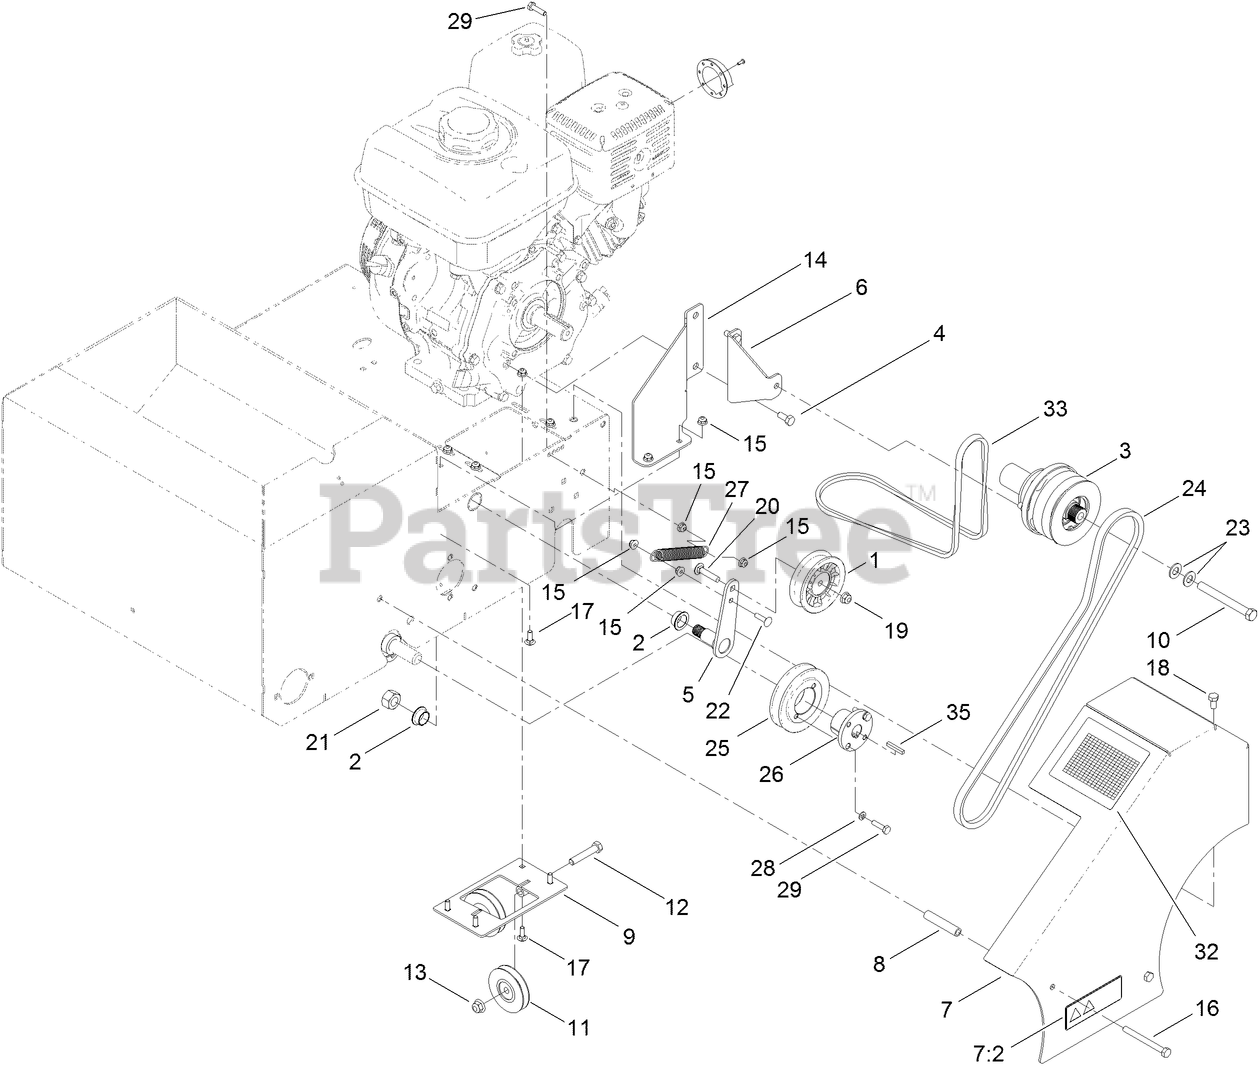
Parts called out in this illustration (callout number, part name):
1	PULLEY-IDLER
2	BUSHING-BRONZE
3	CLUTCH
4	SCREW-HH
5	ARM-IDLER
6	BRACKET-CLUTCH
7	BELT GUARD ASM
7:2	DECAL-DANGER
8	SPACER
9	PULLEY-TENSION
10	SCREW-HH
11	PULLEY-IDLER
12	SCREW-HH
13	NUT-HF, NI
14	GUARD-BELT
15	NUT-HF
16	SCREW-HH
17	BOLT-CARR
18	SCREW-HH
19	NUT-HF, NI
20	BOLT-CARR
21	NUT-HEX
22	SCREW-CARR
23	WASHER-FLAT
24	BELT-DRIVE, CLUTCH
25	SHEAVE-TAPER LOCK
26	BUSHING-TAPER LOCK
27	SPRING-EXTENSION
28	WASHER-LOCK
29	SCREW-HH
32	DECAL-GRAPH, SEED
33	BELT-DRIVE
35	KEY-SQUARE
